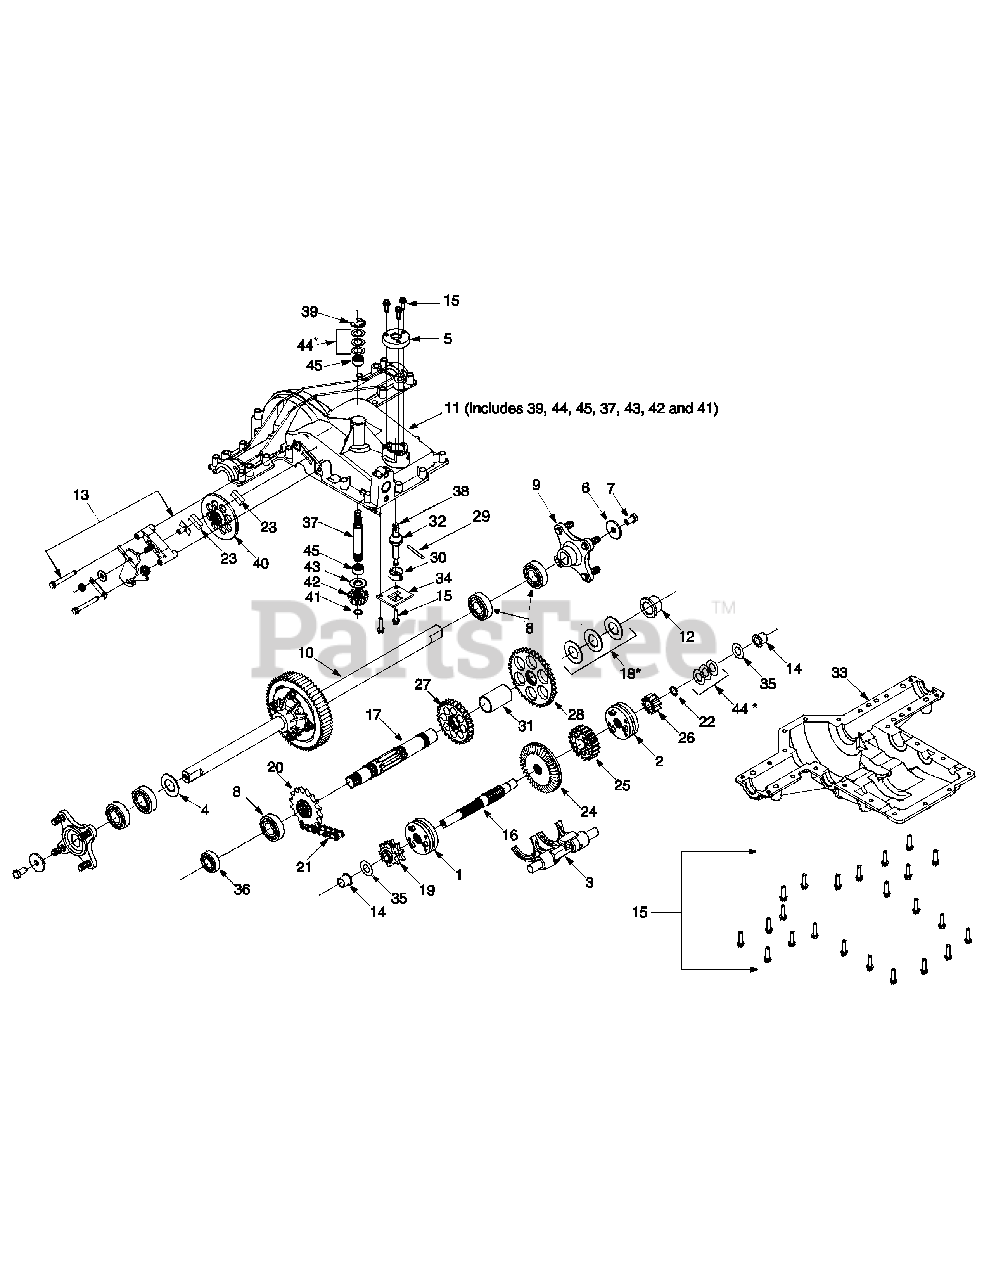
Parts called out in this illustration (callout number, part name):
1	Reverse Collar Assembly
2	Hi-Lo Collar Assembly
3	Shift Fork Assembly
4	Flat Washer, 1.01" x 1.56" x .060"
5	Shifter Cover
6	Flat Washer
7	Lock Bolt, 3/8"-16 x 0.75"
8	Ball Bearing
9	Wheel Hub Assembly, Double D
10	Differential Axle Assembly
11	Upper Housing Assembly
12	Flanged Bearing
13	Brake Assembly
14	Flanged Bearing
15	Self Tapping Screw, 1/4"-20 x 1.00"
16	Drive Shaft
17	Output Shaft
18	Flat Washer, 1.12" x 1.75" x .03"
19	9-Tooth Sprocket
20	16-Tooth Sprocket
21	22 Link Chain, .625 P
22	External Snp Ring
23	Brake Pad
24	41-Tooth Bevel Gear
25	20-Tooth Spur Gear
26	10-Tooth Spur Gear
27	27-Tooth Spur Gear
28	37 Tooth Spur Gear
29	Dowel Pin
30	Shifter Insert
32	Spherical Bearing, 1.00"
33	Lower Housing
34	Lockout Plate
35	Flat Washer, .656" x 1.25" x .02"
36	Oil Seal, 1.00" Shaft x 1.499" Bore
37	Input Shaft
38	Shift Lever
39	E-Ring, .75"
40	Disc Brake
41	Retaining Ring, .56" Dia. Shaft
42	13-Tooth Bevel Gear
43	Flat Washer,
44	Flat Washer, 5/8" x 1.0" x .030"
45	Needle Bearing
